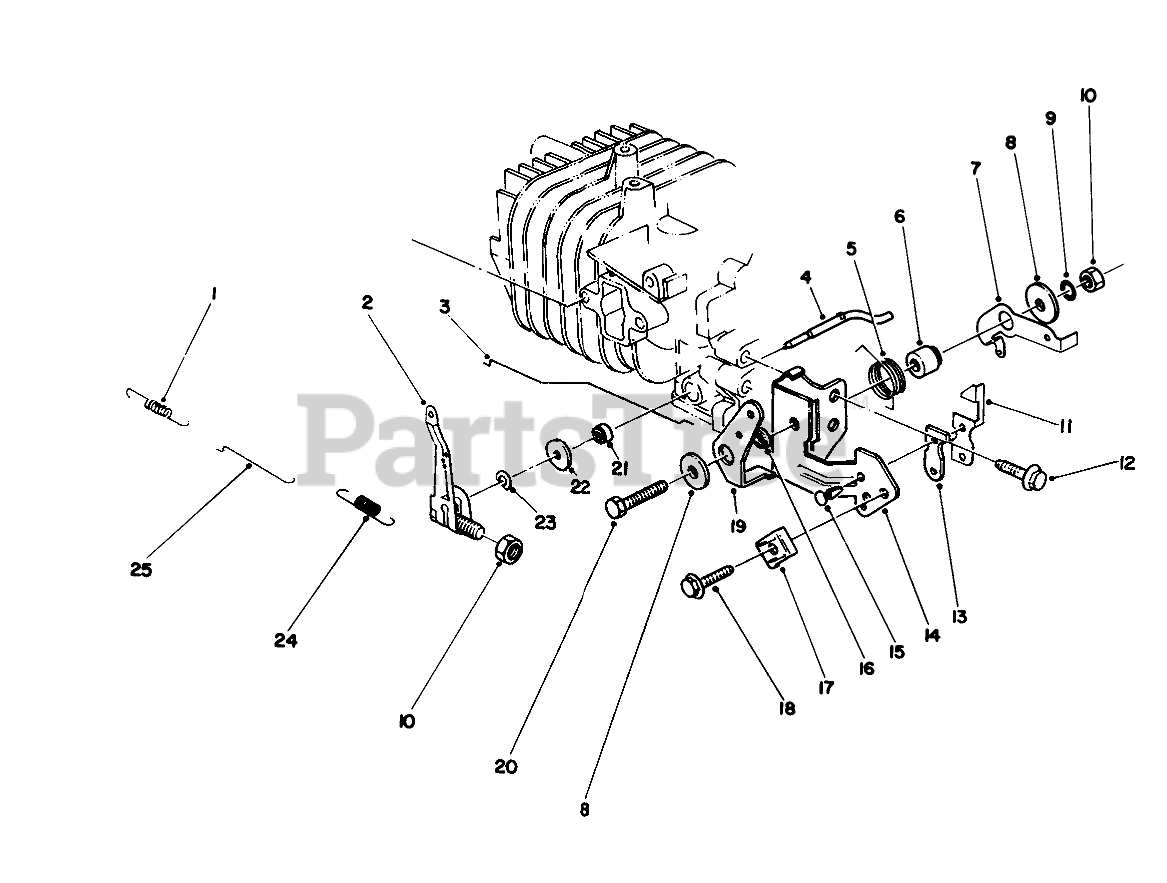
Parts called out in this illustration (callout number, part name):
1	SPRING
2	GOVERNOR ARM
2	ARM-GOVERNOR
3	CHOKE ROD
3	ROD-CHOKE
4	Shaft-Govemor
5	SPRING-CHOKE LEVER
6	Gov Lever Spacer
7	LEVER-SPRING, GOVERNOR
8	WASHER
9	LOCKWASHER
12	TERMINAL-KILL SWITCH
13	INSULATOR-KILL SWITCH
14	BRACKET-THROTTLE, CONTROL
15	KILL SWITCH RIVET
16	SPACER-CHOKE LEVER
17	CLAMP
19	LEVER-CONTROL, CHOKE
21	SEAL-OIL
22	WASHER
23	E-RING
24	SPRING-GOVERNOR
25	ROD-CARBURETOR
